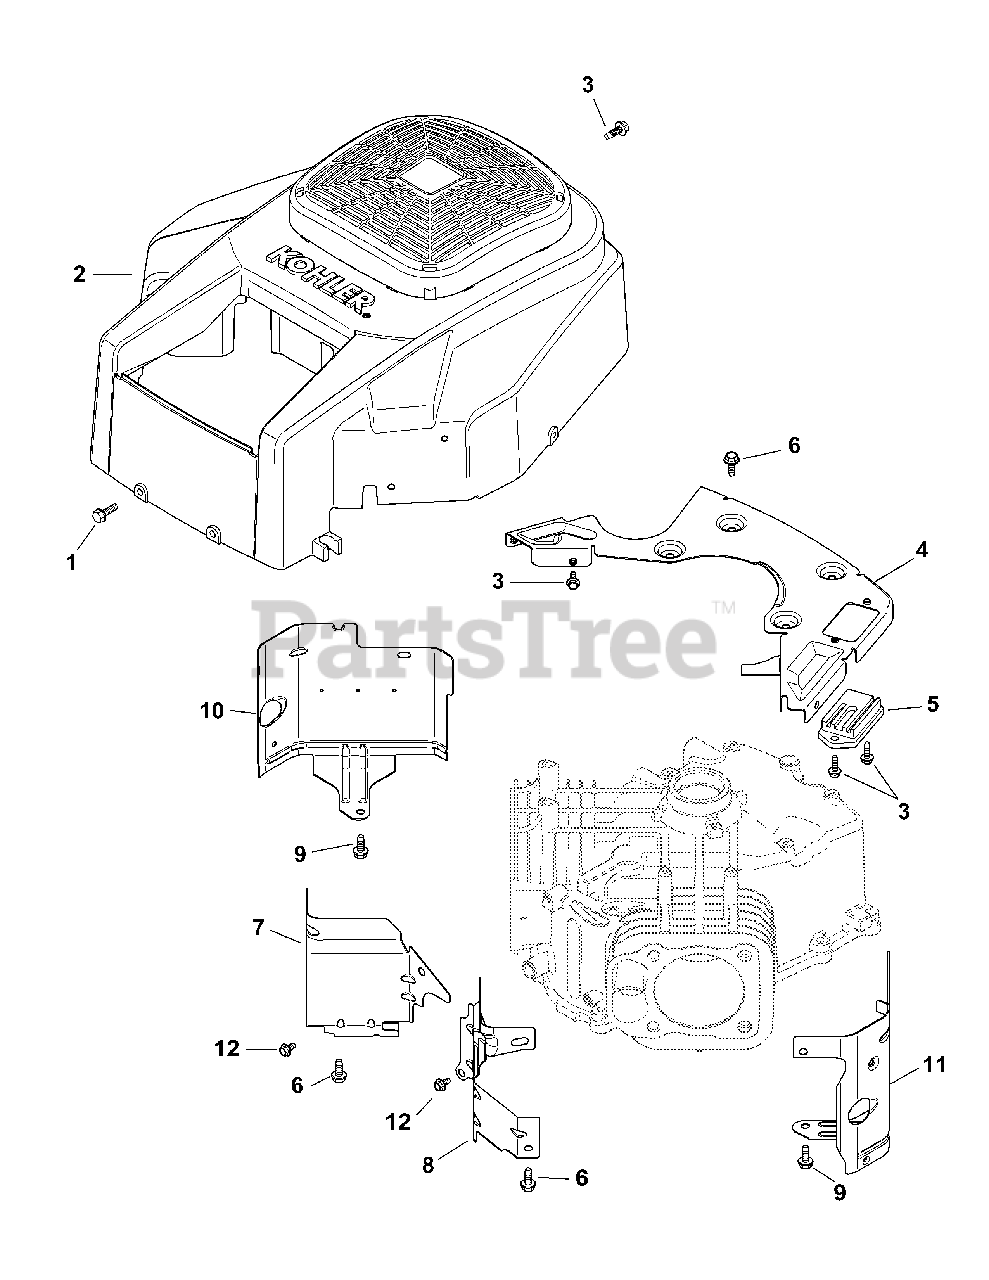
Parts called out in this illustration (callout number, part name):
1	Screw, M6 x 1.7 x 18
2	Blower Housing Kit
3	Flange Screw, M5 x .8 x 16
4	Backing Plate Kit
5	Regulator/Rectifier
6	Flange Screw, M6 x 1.0 x 16
7	Valley Baffle, #1 Cylinder
8	Valley Baffle, #2 Cylinder
9	Flange Screw, M6 x 1.0 x 10
10	Cylinder Barrel Baffle, #1 Side
11	Cylinder Barrel Baffle, #2 Side
12	Flange Screw, M5 x .8 x 10
